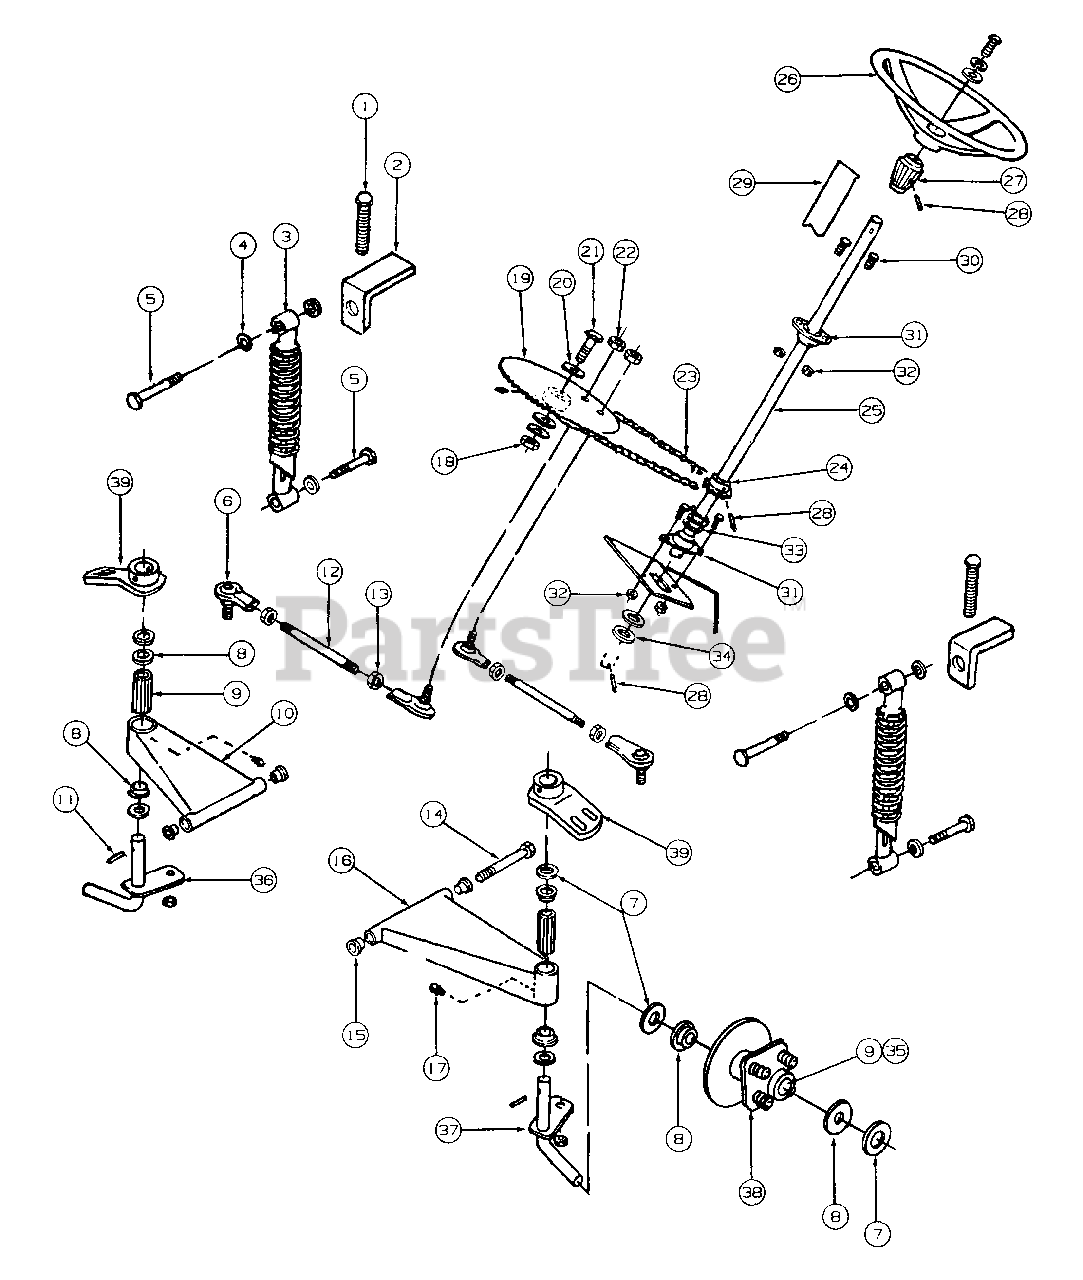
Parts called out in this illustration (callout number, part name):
1	Bolt, Hex Hd, .50-13 UNC X 4.0
2	Bracket, Shock Adjuster
3	Shock, Hydraulic, 12-1/2
4	Washer, .38 X 1.25 X 1.2
5	Screw, Hex Hd Mach, 3/8 X 16 X 2.0
6	Joint, Ball, 1/2
7	Washer, 1.00 X 1.50 X 10 Ga
8	Bearing, Flange, 1
9	Bearing, Roller, 1 X 3
10	Arm Assy, Right A
11	Roll Pin, HBK, .31 X 1.5
12	Tie Rod, Straight
13	Nut, Hex Jam, 1/2-20 UNF
14	Screw, Hex Hd Cap, 5/8-18 X 8 GR5
15	Bearing, Oilite Flange, .625
16	Arm Assy, Left A
17	Fitting, Grease, 45 Degree
18	Nut, Hex Jam, 3/4 X 16
19	Sprocket, B60 X 3/4
20	Washer, Special Flat
21	Screw, Hex Hd Cap, 3/4-16 X 3
22	Nut, Torque Center Lock Hex Jam
23	Chain, 40 X 80 Pitch
24	Sprocket, 40B9
25	Shaft, Steering
26	Steering Wheel
27	Adaptor, Steering Wheel
28	Pin, Spiral Roll, 1/4 X 1-1/2
29	Pad, Steering Shaft
30	Bolt, Hex Hd, .31-24 UNF X .75
31	Bearing, Oilite Flange, 3/4
32	Nut, Center Lock, .31-24 UNF
33	Washer, Shim
34	Washer, Flat
35	Bearing, Roller, 1 X 1.5
36	Spindle, RH
37	Spindle, LH
38	Hub w/Dish Assy, Front
39	Bracket, Brake Mtg
